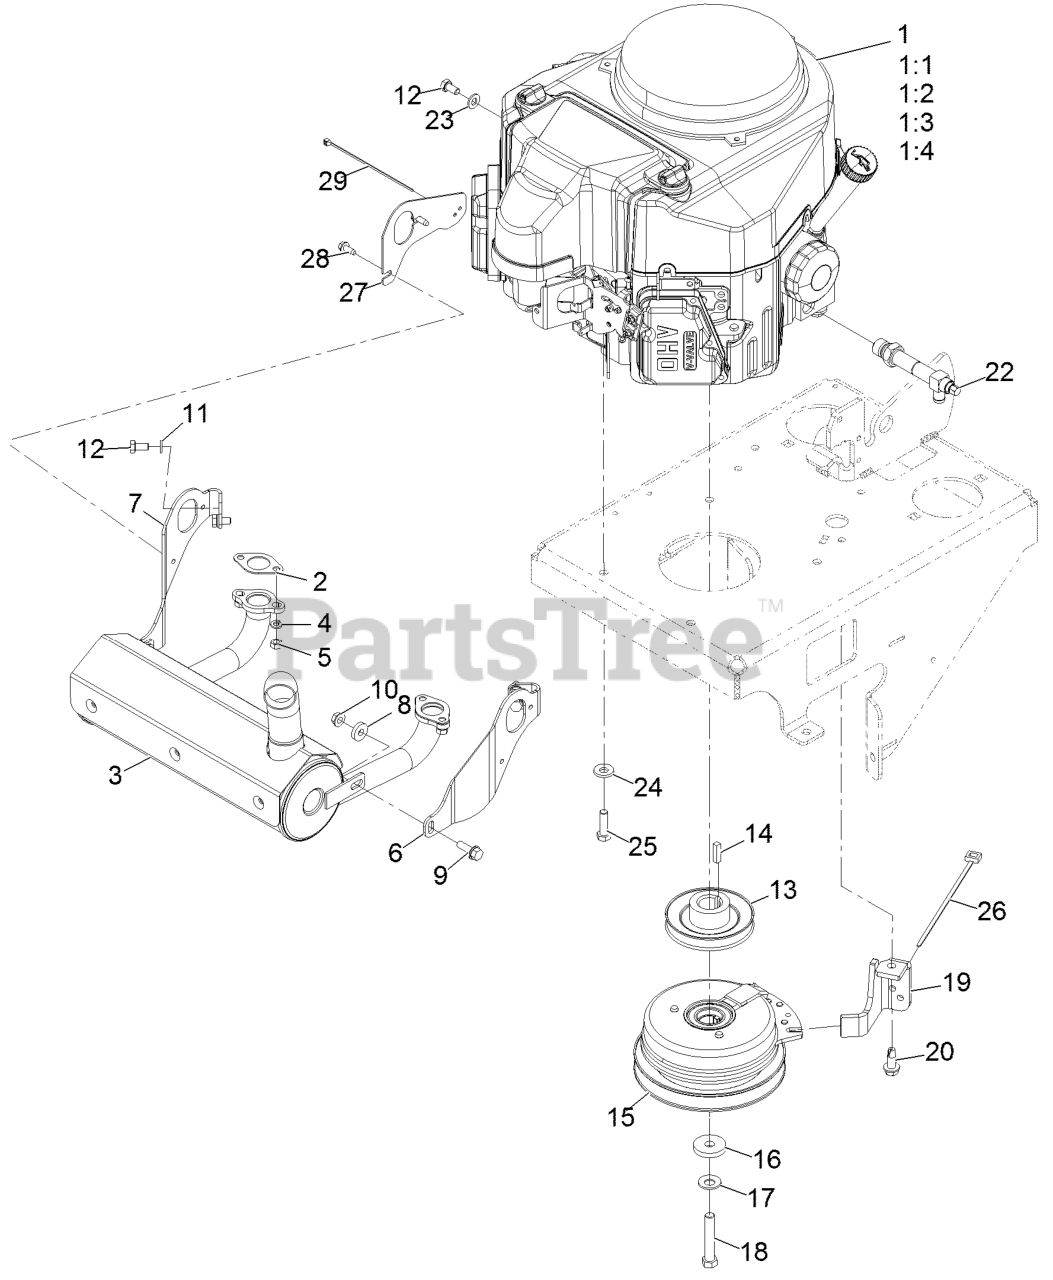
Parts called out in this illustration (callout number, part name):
1:1	SPARK PLUG
1:2	FILTER-OIL
1:3	FILTER-FUEL
1:4	ELEMENT-FILTER, AIR
2	GASKET-EXHAUST
4	WASHER-LOCK
6	BRACKET-MUFFLER MOUNT, LH
7	BRACKET-MUFFLER MOUNT, RH
9	SCREW-HHF
11	WASHER-LOCK
12	SCREW-HH
13	PULLEY
15	CLUTCH-175 FT-LB
16	WASHER
17	WASHER-SPRING
18	SCREW-HH
19	ANCHOR-CLUTCH
20	SCREW-TAPPING
22	DRAIN-OIL, VALVE, KAW
23	WASHER-PLAIN
24	WASHER-BELLEVILLE
25	SCREW-HH
26	TIE-CABLE
27	GUARD-CABLE, SPARK PLUG
28	SCREW-HWH
29	TIE-CABLE
